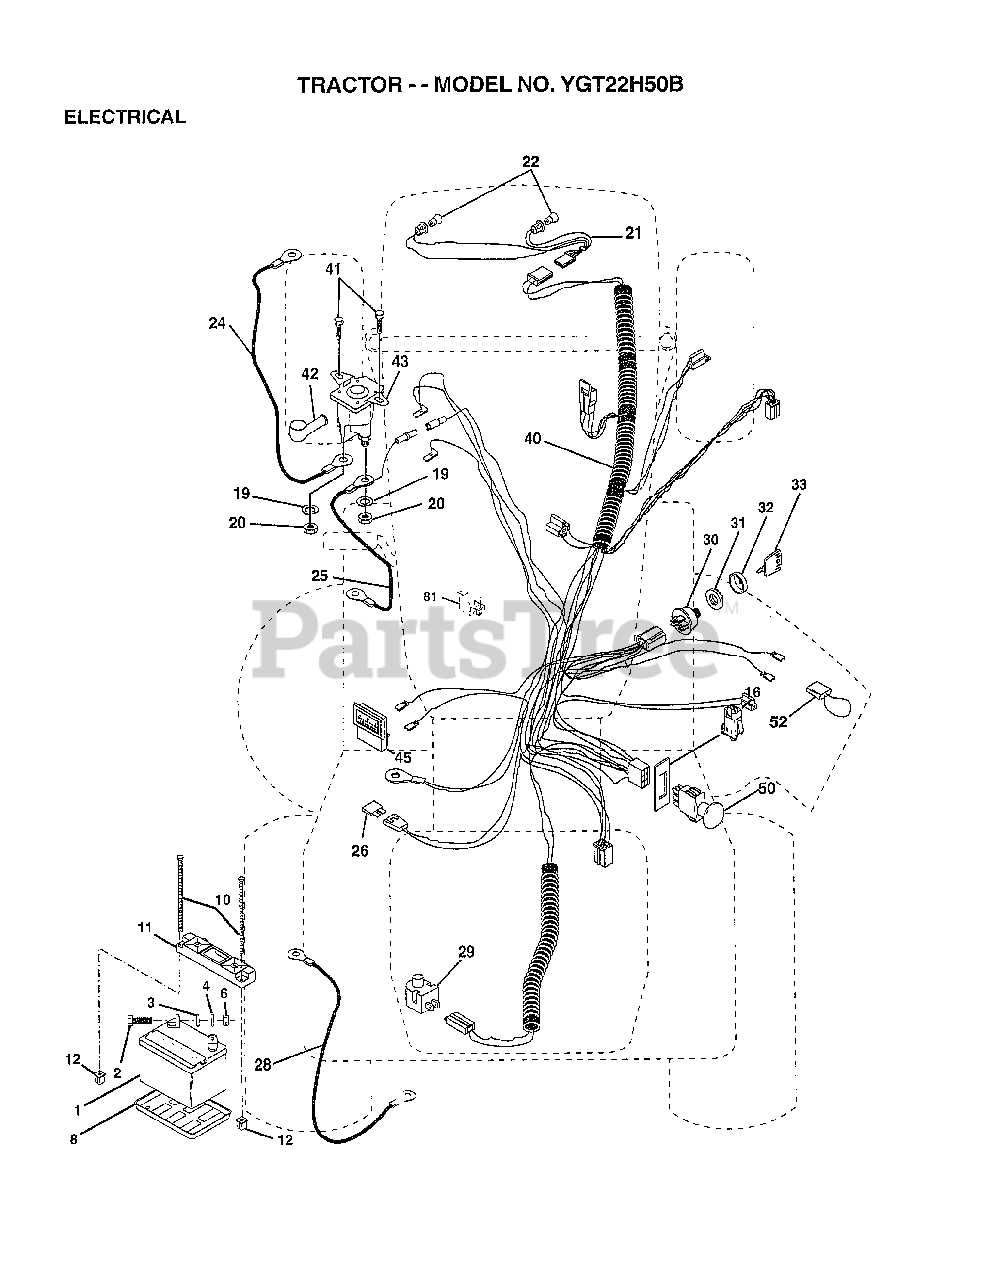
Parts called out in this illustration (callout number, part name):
3	LOCKWASHER
4	WASHER
8	"TRAY T, BATTERY"
11	HOLDDOWN BATTERY
16	SWITCH INTERLOCK
20	NUT
21	"HARNESS,LIGHT SOC"
22	HEADLAMP BULB
24	CABLE.BATY.22.RED
25	CABLE.BATRY.4GA.
26	FUSE HYT
28	"CABLE BATTERY,GRD"
29	SWITCH.PLUNGER
30	SWITCH IGN 4POS
31	NUT IGNITION
32	COVER KEY SWITCH
33	KEY
40	HARNESS.IGN.
41	SCREW
45	AMMETER
50	PTO SWITCH.BLK
51	RING RETAIN PTO
52	PROTECTION LOOP
81	RELAY ASSY T
